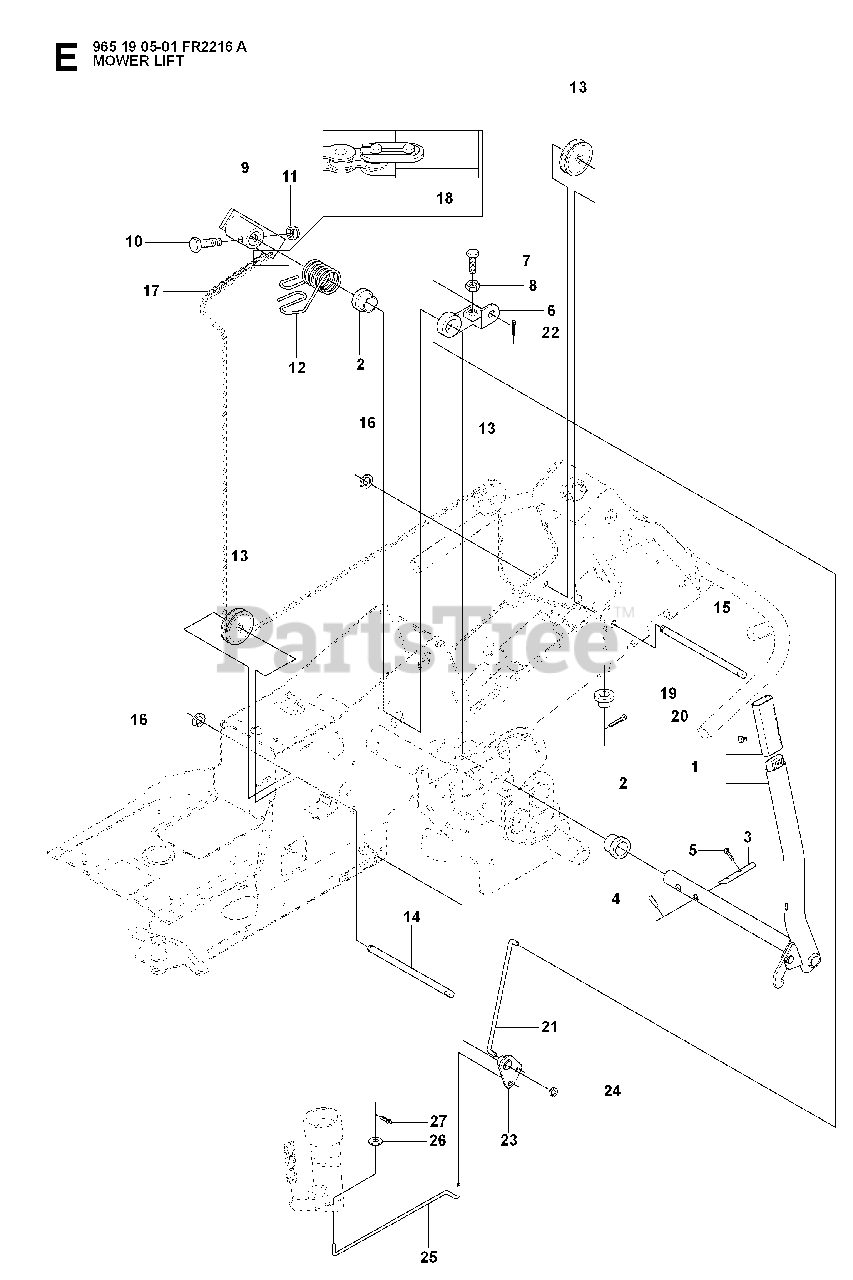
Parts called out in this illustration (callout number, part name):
1	LIFTING LEVER ASSY
2	BUSH
3	RP PIN
5	SPLIT PIN
6	LEVER CLUTCH
16	LOCK RING
20	COTTER PIN
21	CONNECTION ROD
22	SPLIT PIN
24	RETAINING RING
25	CONNECTION ROD
27	SPLIT PIN
